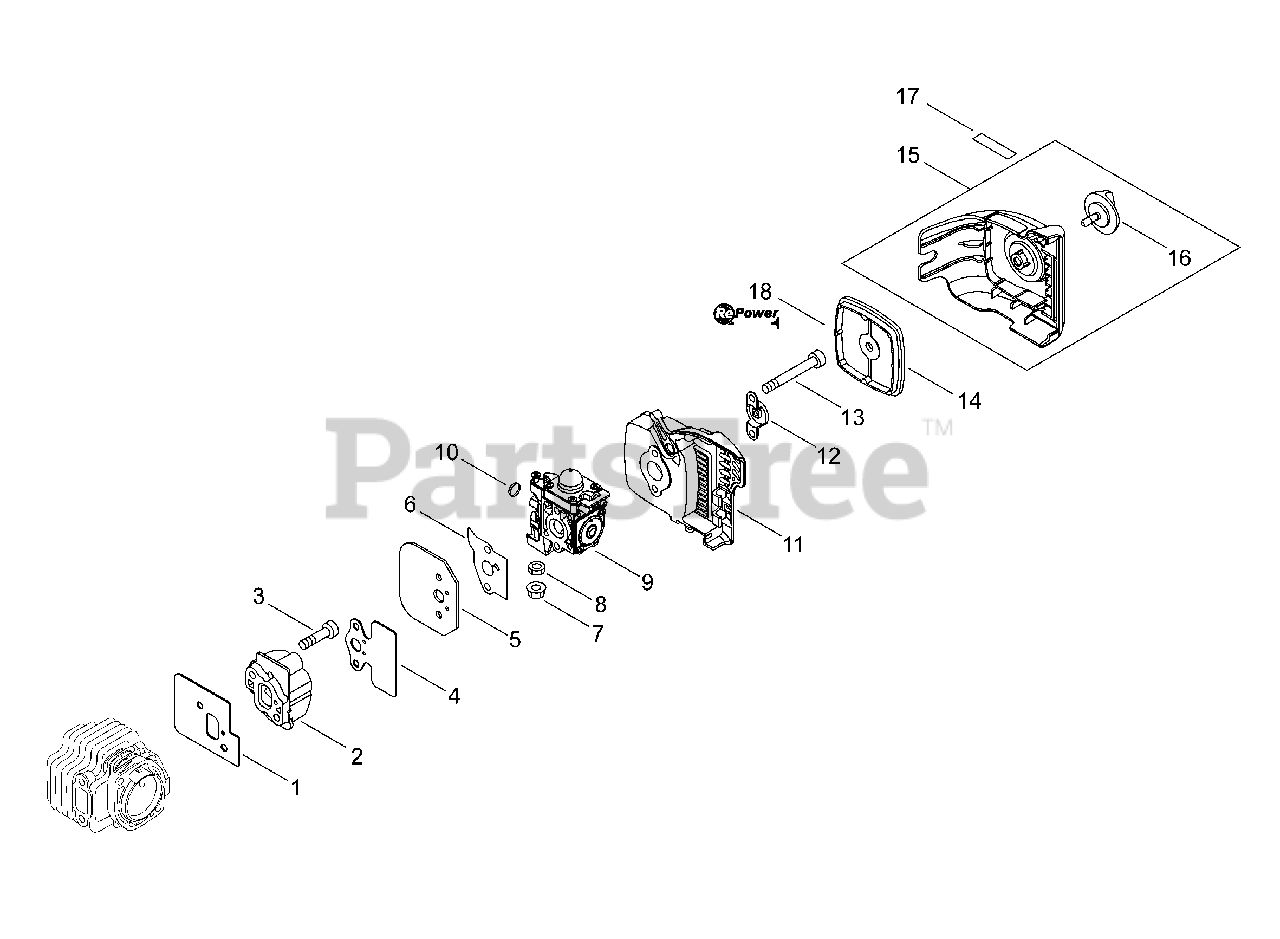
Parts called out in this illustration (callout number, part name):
1	GASKET,INTAKE
2	INSULATOR, INTAKE
3	BOLT, TORX 5
4	GASKET,INTAKE
5	PLATE, INSULATOR
6	GASKET,INTAKE
7	NUT, FLANGE
8	NUT 6 (3N)
9	CARBURETOR,DIAPHRAGM
11	CASE,CLEANER
12	PLATE,PREVENT
13	BOLT, TORX 5
14	ELEMENT,AIR FILTER
15	CLEANER COVER ASY
16	KNOB,FASTENER
17	LABEL, CHOKE
18	FILTER KIT - REPOWER
